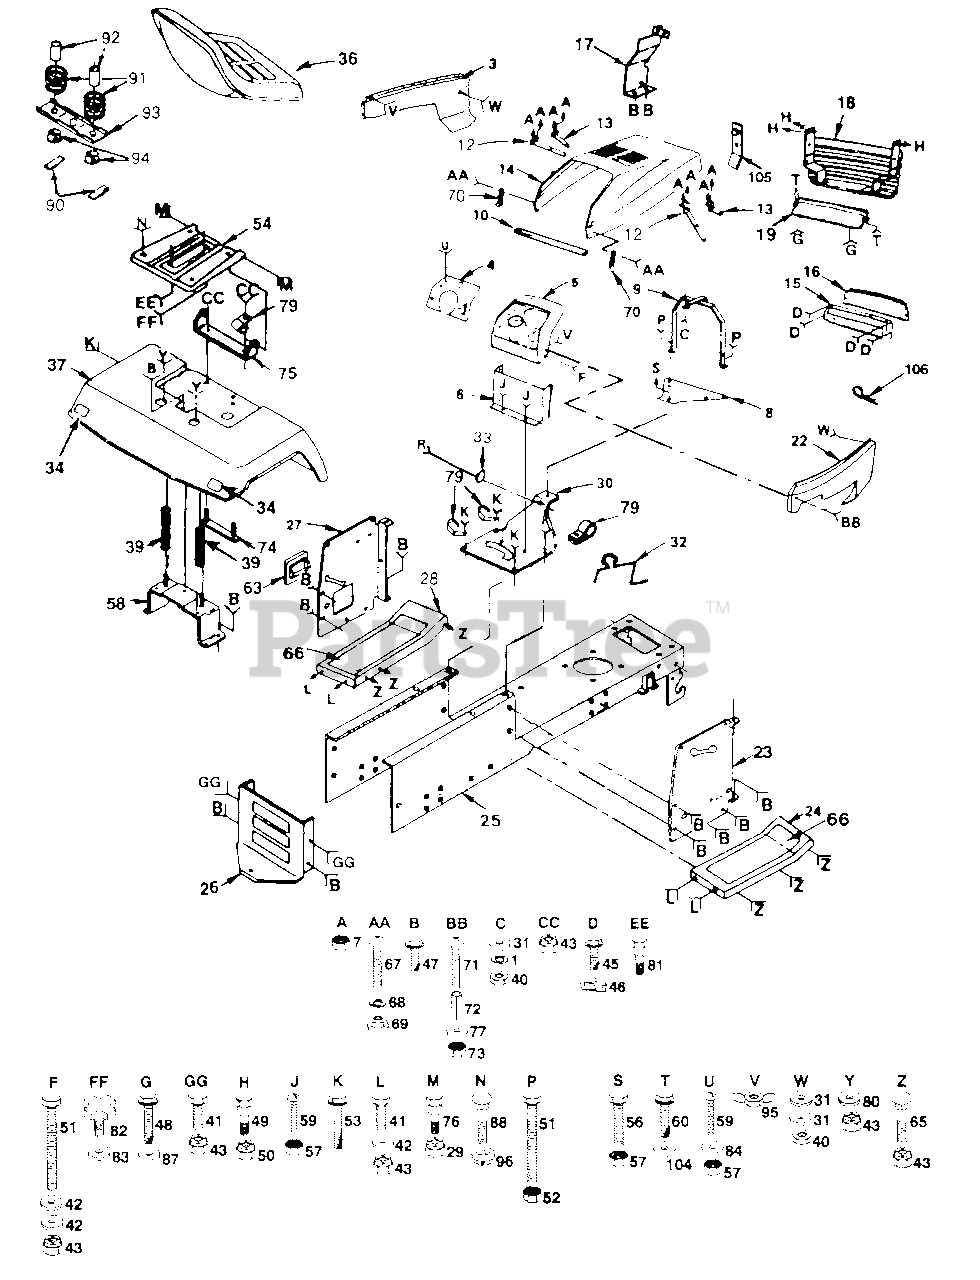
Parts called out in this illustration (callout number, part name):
1	Washer, Lock 1/4 (AYP part number)
3	Panel, Side, L.H. (AYP part number)
4	Plate, Dash (AYP part number)
5	Dashboard (AYP part number)
6	Assembly, Dash, Lower (AYP part number)
7	Nut, Hex Keps 3/8-16 UNC (AYP part number)
8	Plate, Support, Battery (AYP part number)
9	Assembly, Support, Dash (AYP part number)
10	Foam, Strip (AYP part number)
12	Assembly, Strap, Hinge, Rear (AYP part number)
13	Assembly, Strap, Hinge, Front (AYP part number)
14	Hood (AYP part number)
15	Assembly, Bezel
16	Lens (AYP part number)
17	Bracket, Ass'y., Frame, Pivot, L.H.
18	Assembly, Grill
19	Strap, Grill (AYP part number)
20	Bracket, Ass'y., Frame, Pivot, R.H. (AYP part number)
22	Panel, Side, R.H. (AYP part number)
23	Panel, Dash, R.H.
24	Footrest, R.H. (AYP part number)
25	Chassis (AYP part number)
26	Drawbar (AYP part number)
27	Panel, Dash, L.H. (AYP part number)
28	Footrest, R.H. (AYP part number)
29	Nut, Crownlock 5/16-18
30	Saddle (AYP part number)
31	Washer 9/32 x 3/4 x 16 Ga. (AYP part number)
32	Guide Belt (AYP part number)
33	Bushing, Steering (AYP part number)
34	Reflector, Taillight (AYP part number)
36	Seat (AYP part number)
37	Fender (AYP part number)
39	Spring, Seat (AYP part number)
40	Nut, Hex 1/4-20 (AYP part number)
41	Bolt, Hex 3/8-16 x 3/4 (AYP part number)
42	Washer 13/32 x 13/16 x 3/4 (AYP part number)
43	Nut, Crownlock 3/8-16
45	Screw, Hex Wsh. Hd. Tap. #10-16 x 5/8 (AYP part number)
46	"J" Fastener (AYP part number)
47	Screw, Hex Washer Head, Thread Rolling 3/8-16 x 2/4 Type TT (AYP part number)
48	Screw, Hex Washer Head, Thread Rolling 5/16-18 x 3/4 Type TT
49	Bolt, Shoulder 1/4-20 (AYP part number)
50	Nut, Crownlock 1/4-20 (AYP part number)
51	Bolt, Hex 3/8-16 x 1-1/4 (AYP part number)
52	Nut, Keps 3/8-16 (AYP part number)
53	Screw, Hex Washer Head, Thread Forming 3/8-16 x 1/2 Type TT (AYP part number)
54	Pan, Seat (AYP part number)
56	Bolt, Hex 5/16-18 x 3/4 Grade 5 (AYP part number)
57	Nut, Keps 5/16-18 (AYP part number)
58	Assembly, Bracket, Fender (AYP part number)
59	Screw, Truss Head 5/16-18 x 3/4 (AYP part number)
60	Screw, Hex Washer, Head 1/4-20 x 3/4 (AYP part number)
63	Cover, Access (AYP part number)
64	Washer 13/32 x 1-1/4 x 12 Ga. (AYP part number)
65	Bolt, Carriage 3/8-16 x 3/4 (AYP part number)
66	Pad, Footrest (AYP part number)
67	Screw, Cross Recess Pan Head Machine #10-24 x 1/2 (AYP part number)
68	Washer, Lock #10 (AYP part number)
69	Nut, Weld (AYP part number)
70	Latch, Hood (AYP part number)
71	Screw, Machine Cross Recess #10-24 x 1-1/4 (AYP part number)
72	Spacer, Split 10 x 3/4 (AYP part number)
73	Nut, Keps 10-24 (AYP part number)
74	Assembly, Strap, Fender (AYP part number)
75	Bracket, Pivot, Seat (AYP part number)
76	Bolt, Shoulder (AYP part number)
77	Washer 7/32 x 1/2 x 18 Ga. (AYP part number)
79	Clip, Line, Fuel (AYP part number)
80	Washer 13/32 x 1 x 14 GA (AYP part number)
81	Bolt, Shoulder 5/16 x 18 x .62 (AYP part number)
82	Knob 1/2" (AYP part number)
83	Washer 17/32 x 13/16 x 12 Ga. (AYP part number)
84	Washer 11/32 x 11/16 x 16 Ga. (AYP part number)
87	Washer 13/32 x 3/4 x 10 Ga. (AYP part number)
88	Bolt, Carriage 1/4-20 x 1-1/4 (AYP part number)
90	Strip, Foam (AYP part number)
91	Spring (AYP part number)
92	Spacer (AYP part number)
93	Bracket, Mount, Switch (AYP part number)
94	Bushing, Snap (AYP part number)
95	Nut, Wing 14-20 (AYP part number)
96	Nut, Hex Large Flange, Lock (AYP part number)
104	Washer, 9/32 x 3/8 x 16 Ga. (AYP part number)
105	Tab, Grill
106	Retainer, Spring (AYP part number)
